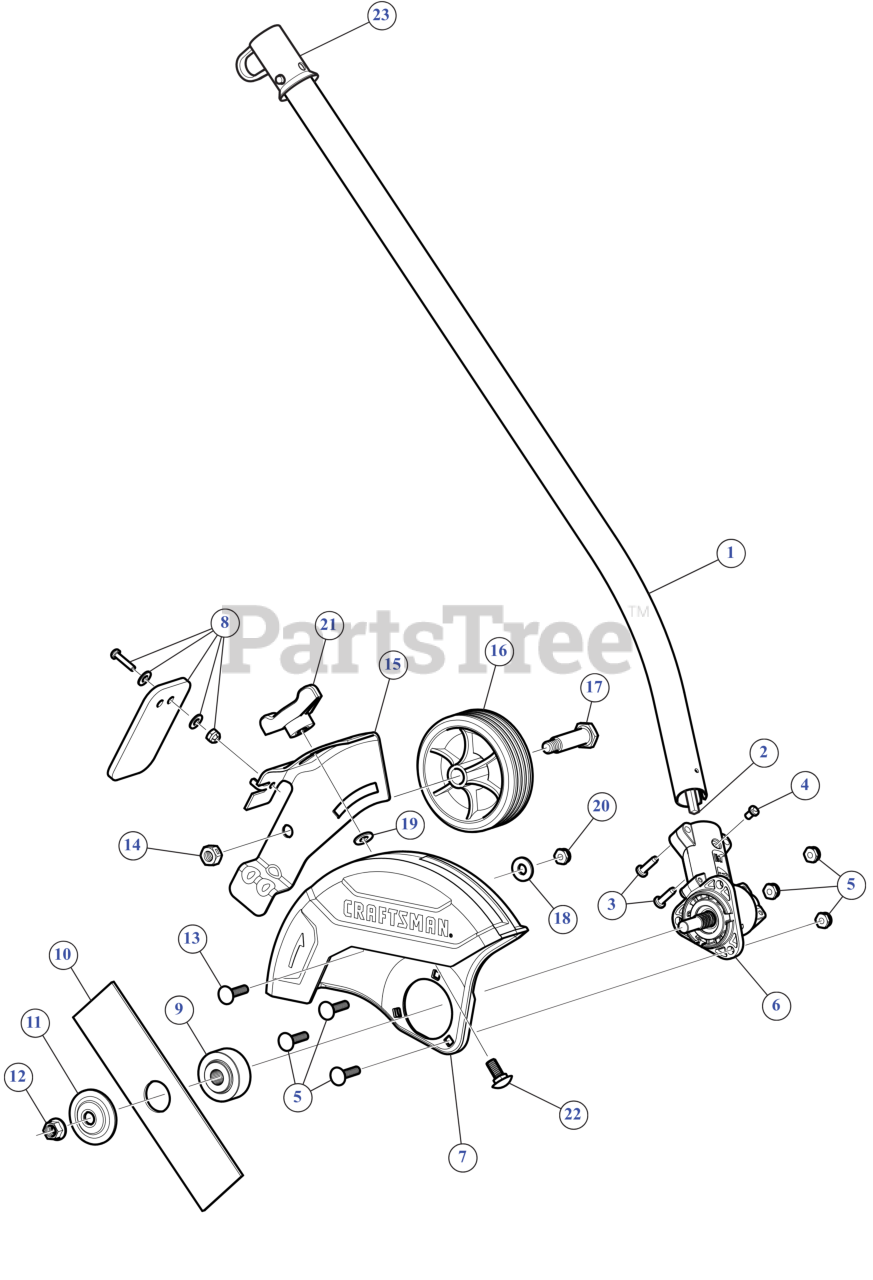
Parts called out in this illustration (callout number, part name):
1	BOOM ASSEMBLY
2	LOWER DRIVE SHAFT
3	SCREW #10-24X11/16 T-25
4	SCREW, 8-32 x .312 P
5	HDWR ASM:GUARD MT
6	GRBX ASSEMBLY
7	EDGER GUARD
8	DEFLECTOR W/HDW
9	SPACER
10	8" EDGER BLADE
11	WASHER-BLADE CLAMP BRUSH CUT
12	BLADE LOCK NUT
13	CARRIAGE BOLT 1/4-20 x 1
14	LOCK NUT 3/8-16
15	BRACKET GUARD
16	WHEEL 3.75" (WHITE)
17	SHOULDER SCREW 0.498x1.494 3/8-16
18	FLAT WASHER
19	WASHER .406X1.0X.095
20	NUT 1/4-20 NYLOC
21	WING KNOB 5/16-18
22	CARRIAGE BOLT 5/16-18 x .75
23	HANGER
